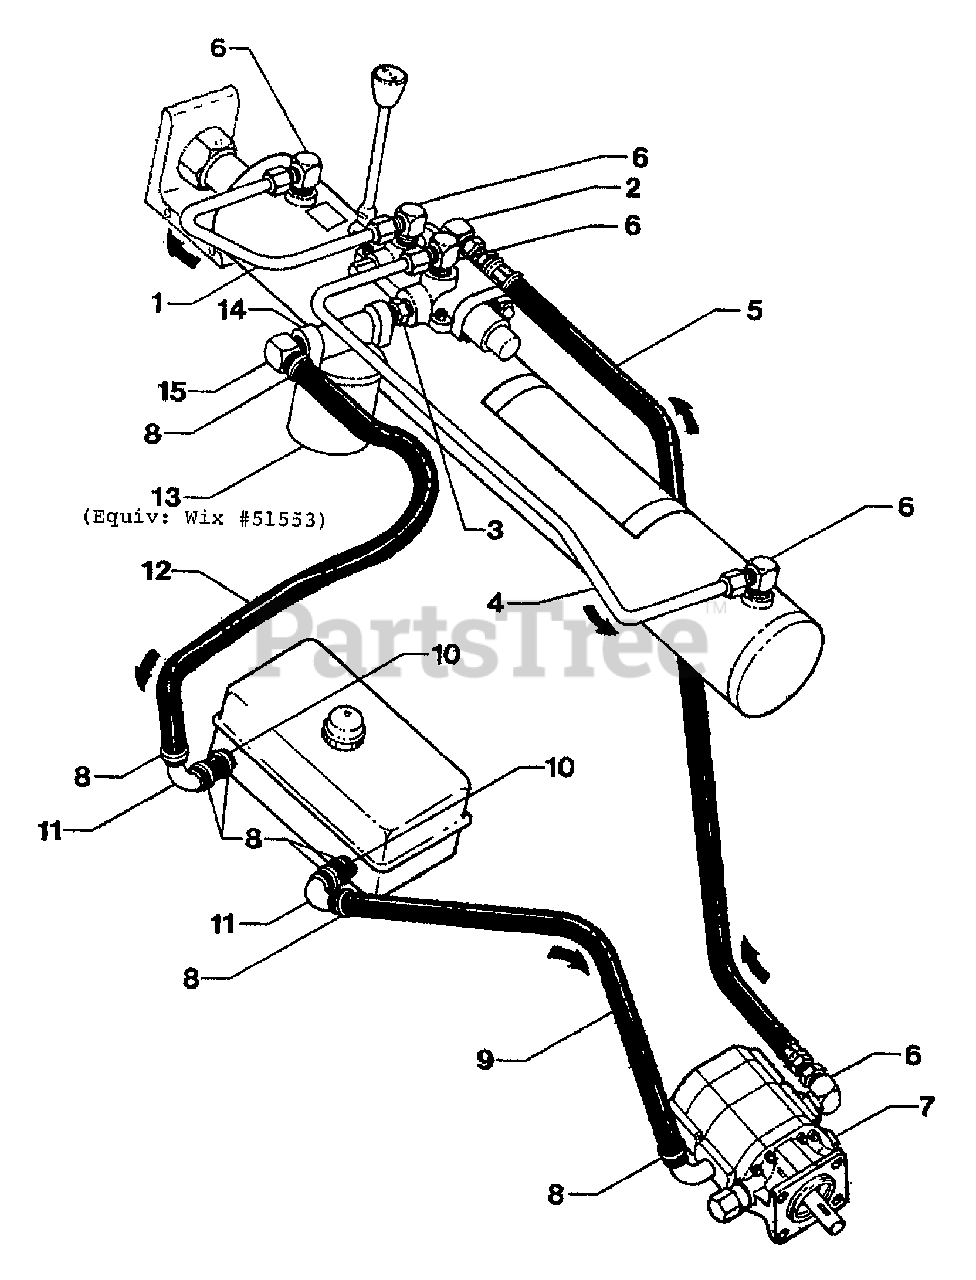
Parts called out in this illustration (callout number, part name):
1	TUBE-SHORT (CYLINDER)
2	ELBOW-90-3/4NPTF X 3/4-16
3	NIPPLE 3/4-14 NPTF
4	TUBE-LONG (CYLINDER)
5	ASSM-HOSE HIGH PRESSURE
6	ELBOW-MALE .5NPTF X .75
7	KIT-PUMP ASSM LOGSPLITTER
9	HOSE-SUCTION 5/8"X1"X28"
10	CONNECTOR-HOSE
11	ELBOW-TUBE .625 OD.
12	HOSE-SUCTION 5/8"X1"X18"
13	FILTER-OIL CANISTER
14	FILTER-OIL T-TOP
15	ELBOW 1/4-NPFT
